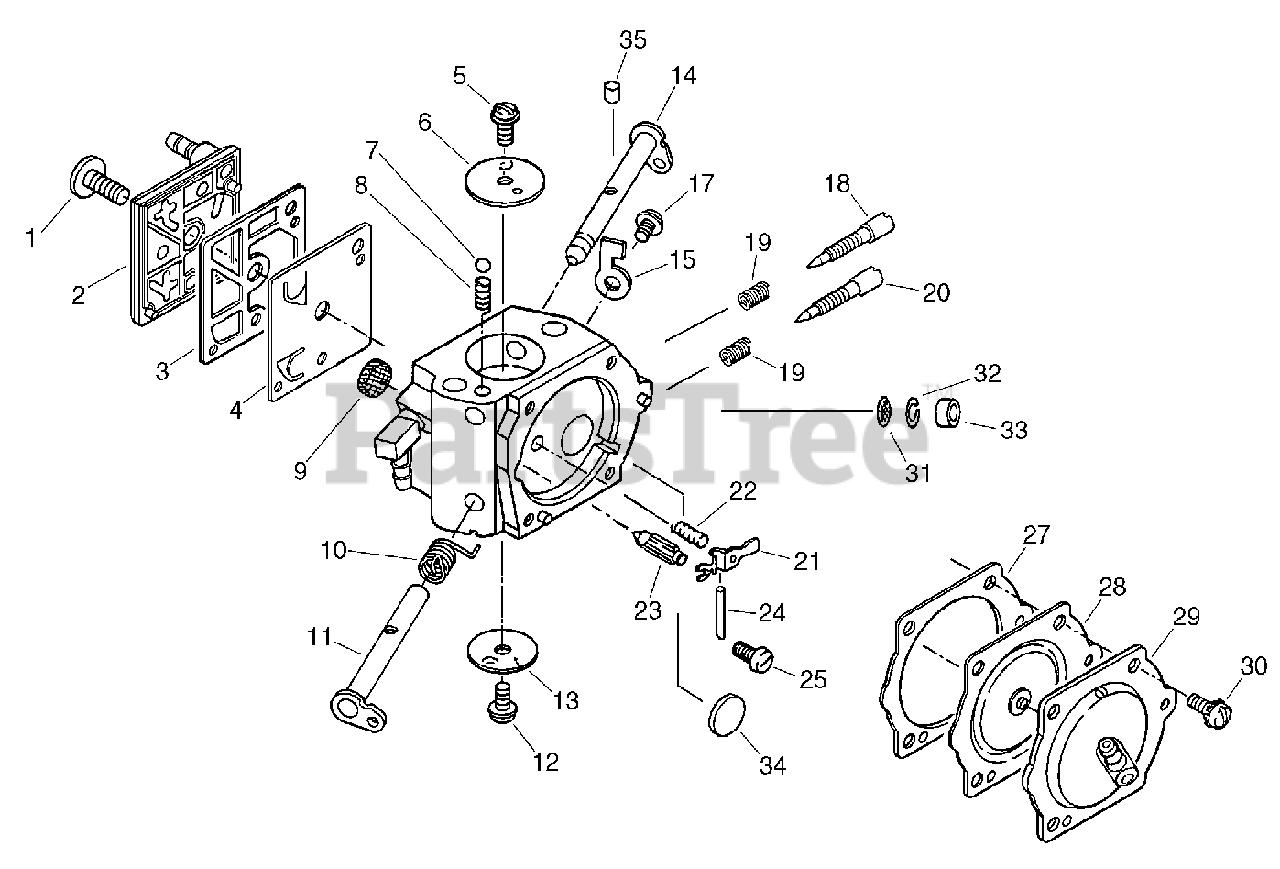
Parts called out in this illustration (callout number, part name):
1	SCREW, PUMP COVER
2	COVER, PUMP
3	GASKET, PUMP
4	DIAPHRAGM, PUMP
6	VALVE, CHOKE
7	BALL, CHOKE
9	STRAINER
10	SPRING, THROTTLE RETURN
11	SHAFT, THROTTLE
13	VALVE, CHOKE
14	SHAFT, CHOKE
15	STOP, THROTTLE
18	NEEDLE - HIGH SPEED
20	NEEDLE - LOW SPEED
21	LEVER, METERING
22	SPRING, METERING LEVER
23	VALVE, INLET NEEDLE
24	PIN, METERING LEVER
25	SCREW, METERING LEVER PIN
27	GASKET, METERING
28	DIAPHRAGM, METERING
29	COVER, METERING
31	SCREEN, SPARK ARRESTOR
32	RING, RETAINING
33	PLUG, WELCH
34	PLUG, WELCH
